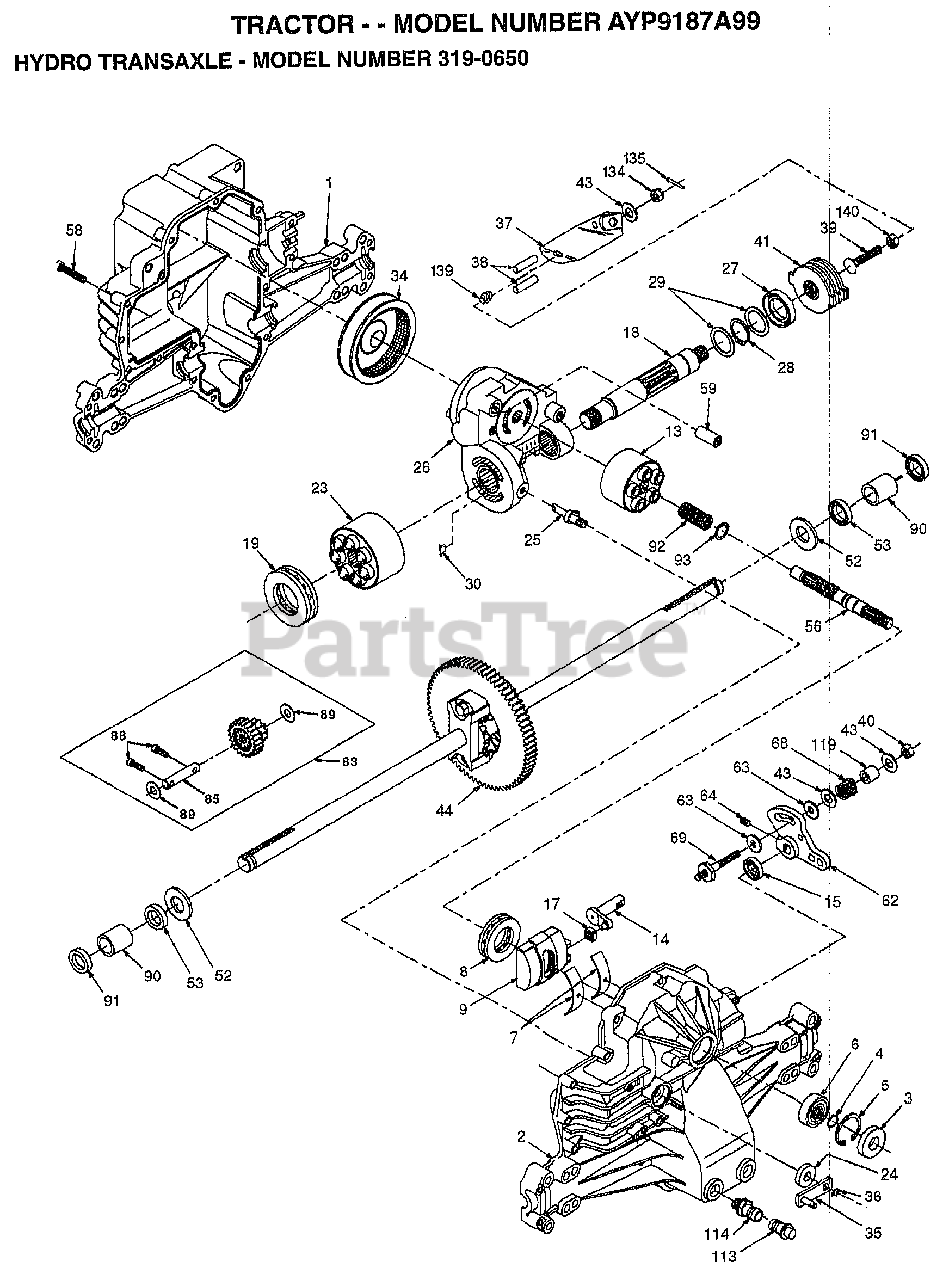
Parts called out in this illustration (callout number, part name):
1	HOUSING.L.50074RM
2	HOUSING.UP.70125
3	SEAL.9008000-0128
4	RING.RET.2003016.
5	RING.RET.2003052.
6	BEARING.(50552)42X68X16
7	CRADLE- 2003023.
8	BEARING.THU.50551
9	SWASHPLT.2003087.
13	BLOCK.CLYN.70079.
14	ARM.TRUN.2003005.
15	SEAL.9008000-0126
17	GUIDE.2000015.
18	SHAFT.MOTOR.50449
19	BEARING.THU.50552
23	BLOCK.CYLIN.70082
24	SEAL.LIP.45074
25	ACTUATOR.2003555
26	KIT.CEN.SEC.70250
27	SEAL.LIP.45075
28	RING RETAIN 50007
29	WASHER.44872
30	PLATE.BYP.2003554
34	ELEMENT.OIL.44964
35	ARM.BYPASS.50270
36	RING.RETAIN.44870
37	ARM.ACTUAT.23710
38	PIN.ACTUAT.44891
39	BOLT.50316
40	NUT.LOCK.HX.50317
41	KIT.BRAKE.70135
43	WASHER HYD 44130
44	DIFFRENTIAL.70226
52	WASHER.HYD.44875
53	SEAL.HYDRO.45076
56	SHAFT.INPUT.50005
58	BOLT.1/4-20.44876
59	PIN.HYDRO.50002
62	ARM.CONTROL.50254
63	PUCK.DAMPER.50281
64	SCREW.SET.50018.
68	SPRING.HYD.50277
69	STUD.5/16-24.DANA
83	JACKSHAFT/PINION GEAR.70132
85	PIN.SHAFT 50559
88	SCREW.CAP.50154.
89	WASHER.HYD.50132
90	BEARING.SLV.50118
91	SEAL.WIPER.50941
92	SPRING.2003014.
93	WASHER.2003017
113	CAP.VENT.70109
114	O-RING.ASM.70110
119	SPACER.HYD.50278
134	NUT.CAS.HYD.44142
135	PIN.COT.HYD.44101
139	SPRING.COMP.50431
140	NUT.HEX.50269
